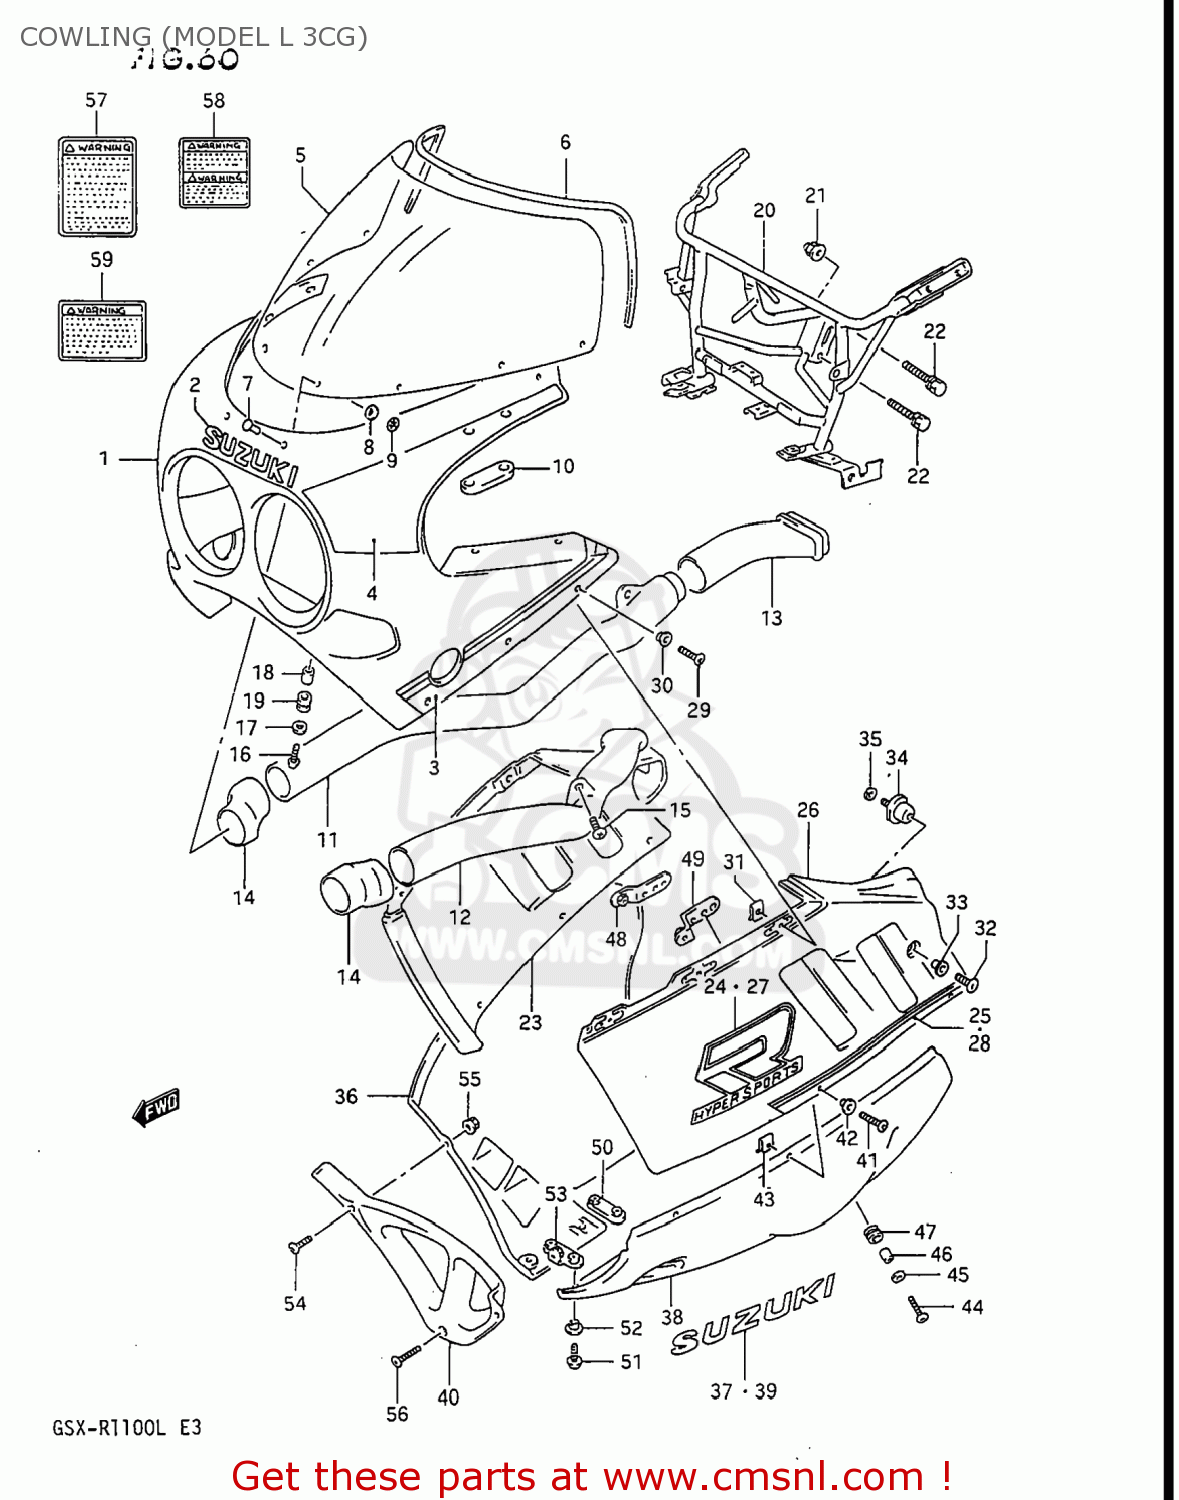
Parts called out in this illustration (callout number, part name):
1	BODY ASSY,COWLING
2	EMBLEM,COWLING FR
3	TAPE SET,COWLING,UPPER
4	TAPE SET,COWLING,UPPER,FRONT
5	SCREEN,WIND
6	MOLDING
7	PIN,WINDSCREEN
8	CUSHION
9	NUT
10	CUSHION,RR VIEW MIRRORR
11	PIPE,AIR INTAKE FR,R
12	PIPE,AIR INTAKE,FRONT
13	PIPE,AIR INTAKE RR,R
14	JOINT,AIR INTAKE
15	SCREW, CENTER
16	SCREW(6X20)
17	WASHER(6.5X18X1)
18	SPACER
19	CUSHION
20	BRACE,COWLING
21	NUT ,8MM
22	BOLT
23	COVER ASSEMBLY,COWLING
24	EMBLEM,COWLING SIDE,R
25	TAPE,COWLING SIDE,RIGHT
26	COVER,COWLING SIDE,LEFT
27	EMBLEM,COWLING SIDE,LEFT
28	TAPE,COWLING SIDE,LEFT
29	SCREW(5X18)
30	WASHER(5.2X14X1.5)
31	NUT,HEADLAMP HOUSING,UPPER
32	SCREW(6X12)
33	WASHER(6.3X16X1.5)
34	CUSHION,COWLING
35	WASHER,LOCK
36	COWLING COMP,UNDER,RIGHT
37	EMBLEM
38	COWLING,UNDER,LEFT
39	EMBLEM,COWLING UNDER,L
40	COWLING,UNDER,CENTER
41	SCREW(5X18)
42	WASHER(5.2X14X1.5)
43	NUT,HEADLAMP HOUSING,UPPER
44	SCREW(6X20)
45	WASHER(6.5X18X1)
46	SPACER
47	CUSHION
48	BRACKET
49	BRACE,COWLING UNDER,LH
50	BRACE,COWLING LWR COVER RR
51	SCREW(6X16)
52	WASHER(6.3X16X1.5)
53	BRACE,COWLING LWR COVER
54	SCREW(5X14)
55	NUT
56	SCREW(6X16)
57	LABEL (WARNING SCREEN)
58	LABEL (WARNING)
59	LABEL
